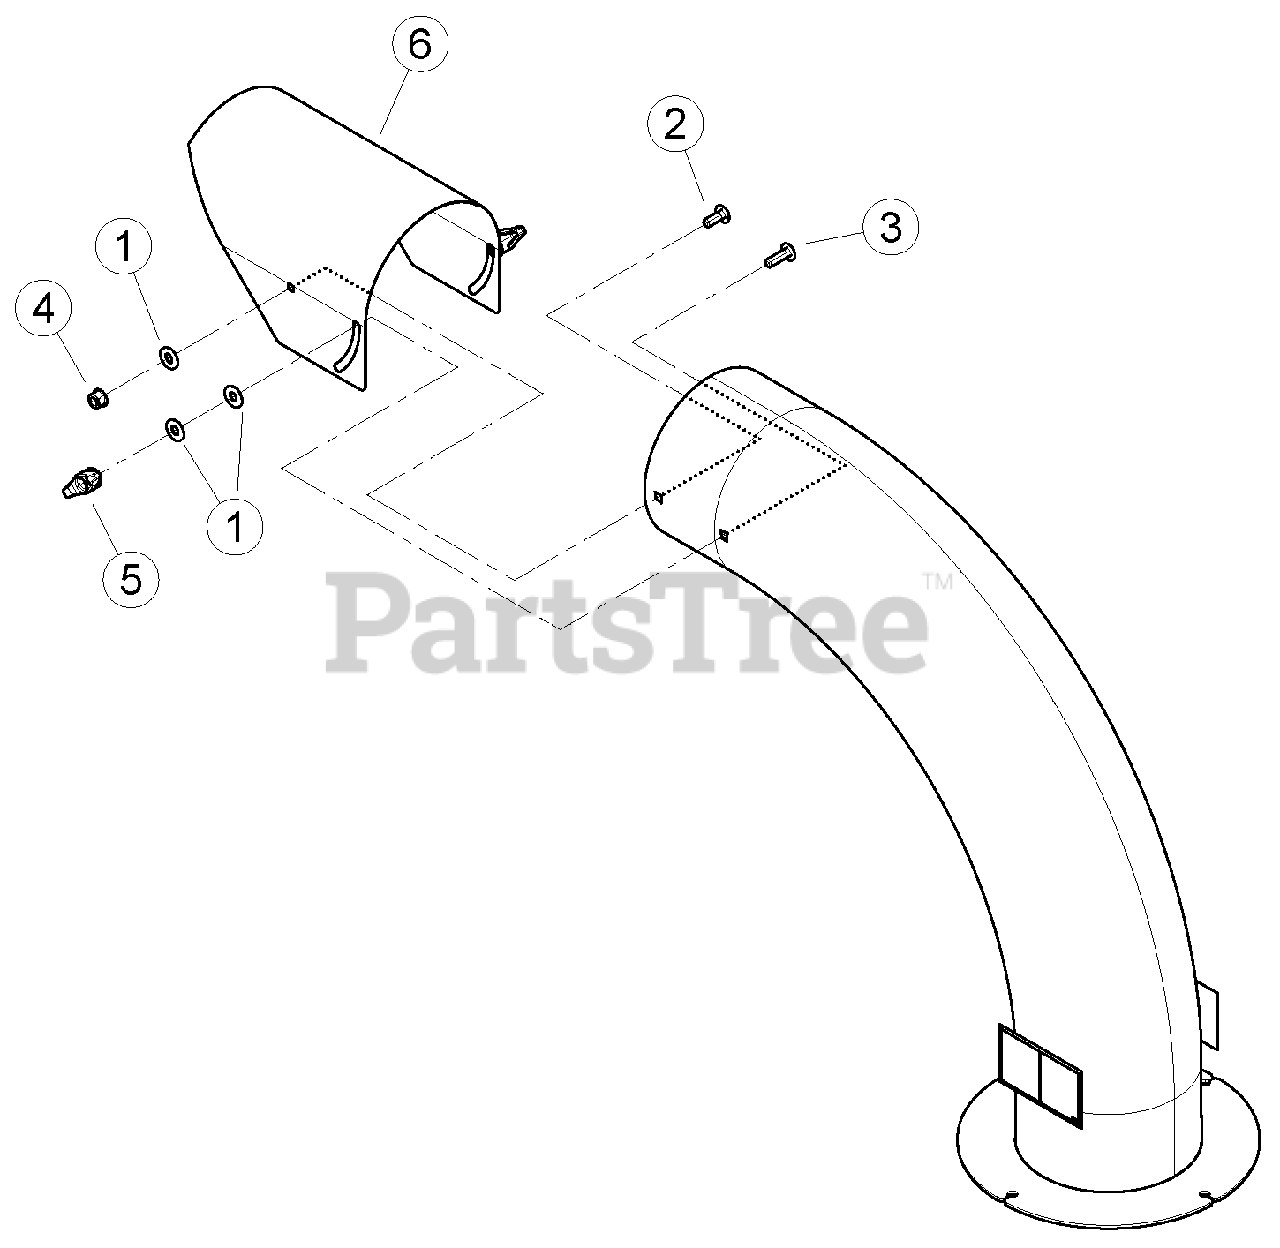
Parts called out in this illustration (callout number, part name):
1	WASHER, 3/8 FLAT
2	BOLT, 3/8-16 X 1 GR5 CRG
3	BOLT, 3/8-16 X 1-1/4 GR5 CRG
4	NUT, 3/8-16 NYLOCK FLANGE
5	KNOB, 3/8-16 UNC FEMALE TEE
6	CAP, 8 INCH DISCHARGE CHUTE
